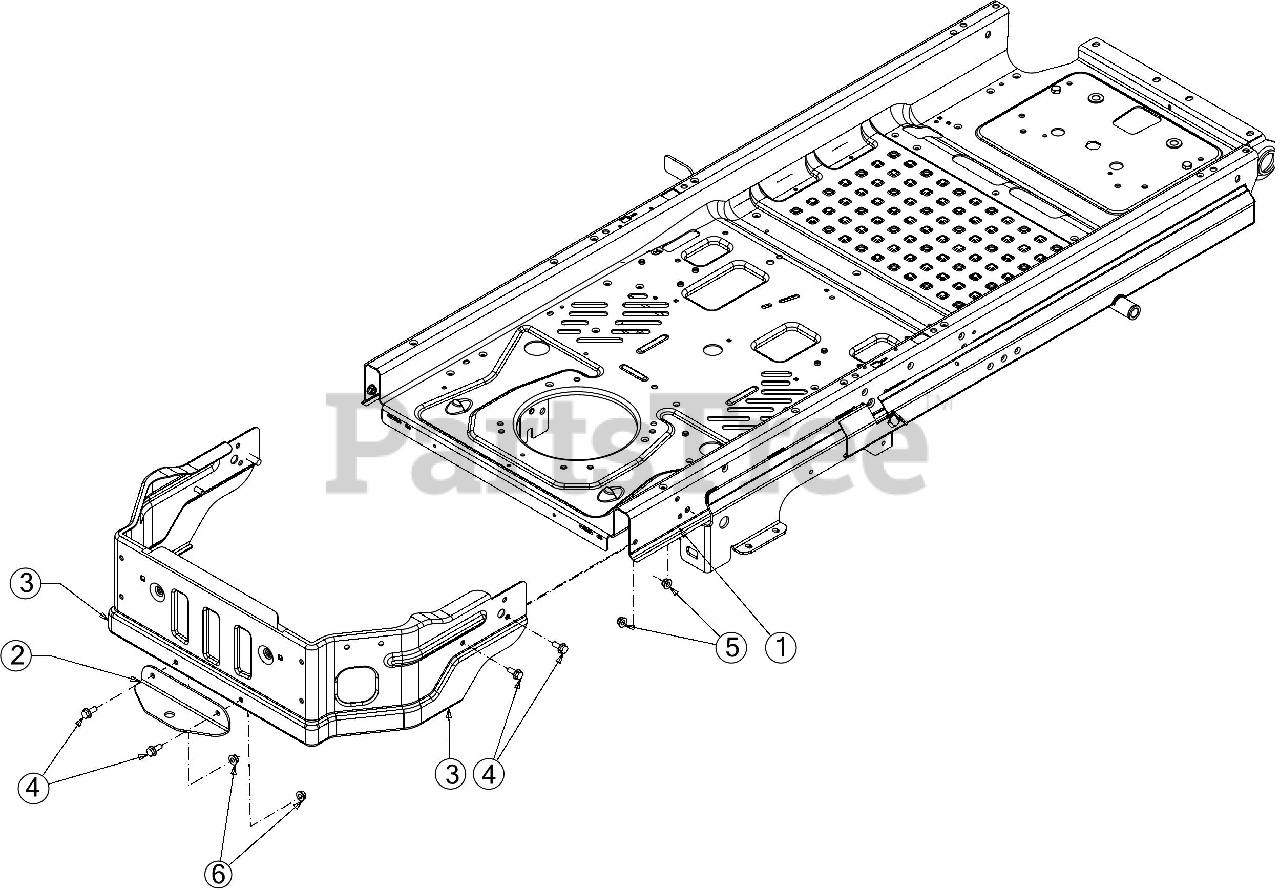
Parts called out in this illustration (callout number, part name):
1	TRANSMISSION MOUNTING BRACKET (LH)
1	TRANSMISSION MOUNTING BRACKET (RH)
1	DECK HANGER BRACKET
1	FLANGE LOCK NUT
1	SCREW 3/8-16 x 1 GR5
1	RZT FRAME
4	SCREW 5/16-18
5	FLANGE LOCK NUT 5/16-18
6	FLANGE NUT
